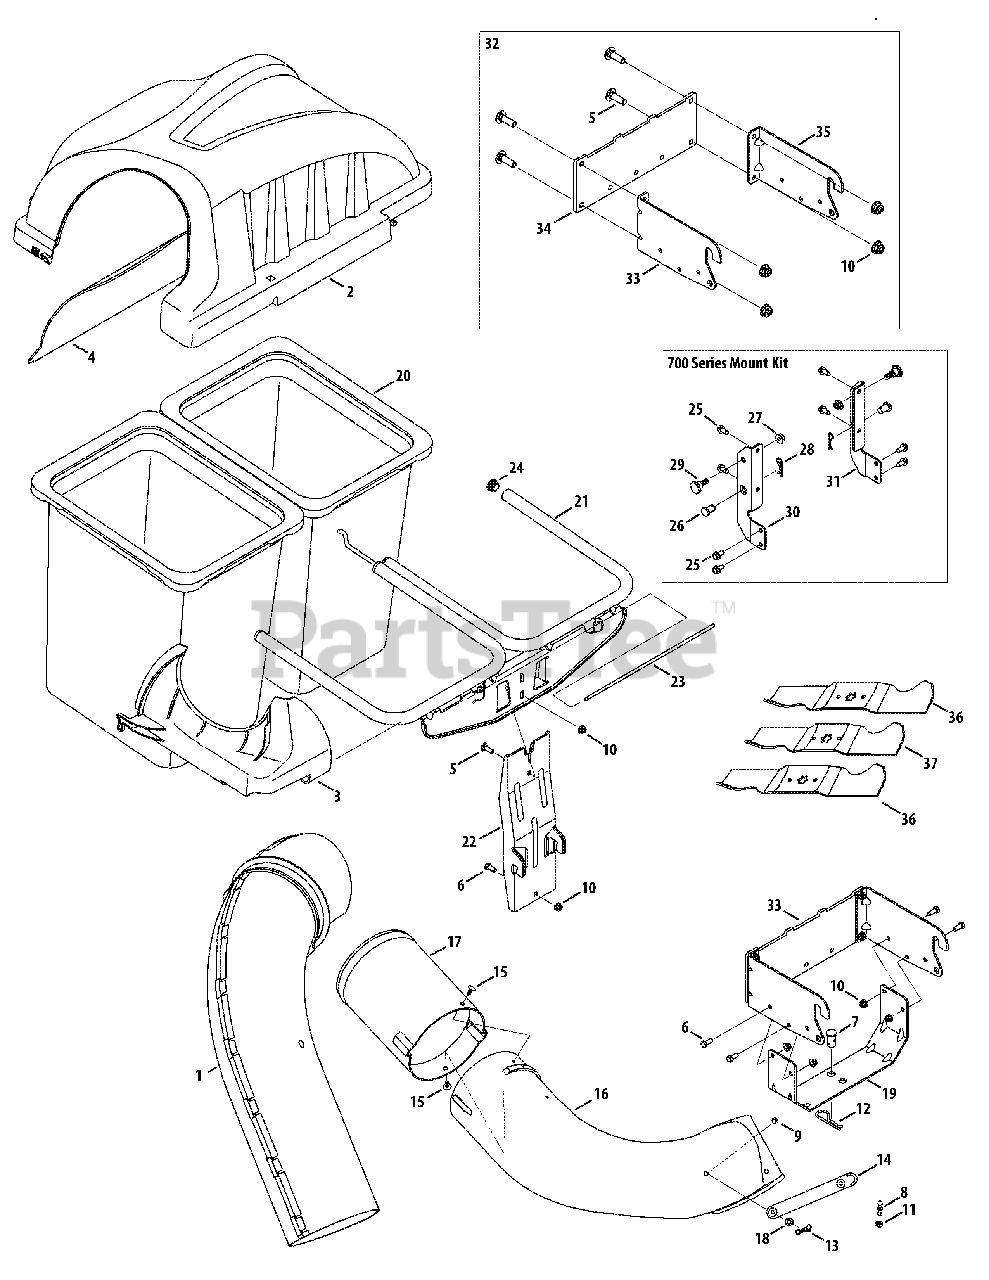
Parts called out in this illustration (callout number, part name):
1	Upper Chute Assembly
2	Double Bagger Cover Assembly
3	Upper Chute Support
4	Bagger Cover Screen
5	Carriage Screw, 5/16-18 x 1.00"
6	Hex Head Screw, 5/16-18 x .75"
7	Clevis Pin, .62" Dia.
8	Grass-catcher Pin, 1/4-20
9	Clevis Pin, 5/16 x .75 Lg.
10	Flange Lock Nut, 5/16-18
11	Flange Lock Nut, 1/4-20
12	Internal Cotter Pin, .148 x 3.00
13	Bow-Tie Cotter Pin, 72
14	Chute Strap, 6.00 Lg.
15	Ratchet Clip, .250
16	Discharge Chute Elbow, 46" Deck
17	Bagger Chute Adapter, 7 In.
18	Flat Washer, .344 x .62 x .033
19	Universal Bracket Support
20	Grass-bag Assembly
23	Cover Hinge Pin
25	Tap Screw, 5/16-18 x .750
26	Clevis Pin, .50 x .78 Lg.
27	Flange Lock Nut, 3/8-16
28	Click Pin, .092 x 1.64 Lg.
29	Shoulder Screw, .625 x .412
32	Hitch Bracket Assembly
33	Hitch Bracket, RH
34	Universal Rear Attachment Bracket
35	Hitch Bracket, LH
36	Blade, 16.28 Lg., Star 2-in-1
37	Blade, 14.88 Lg., Star 2-in-1
